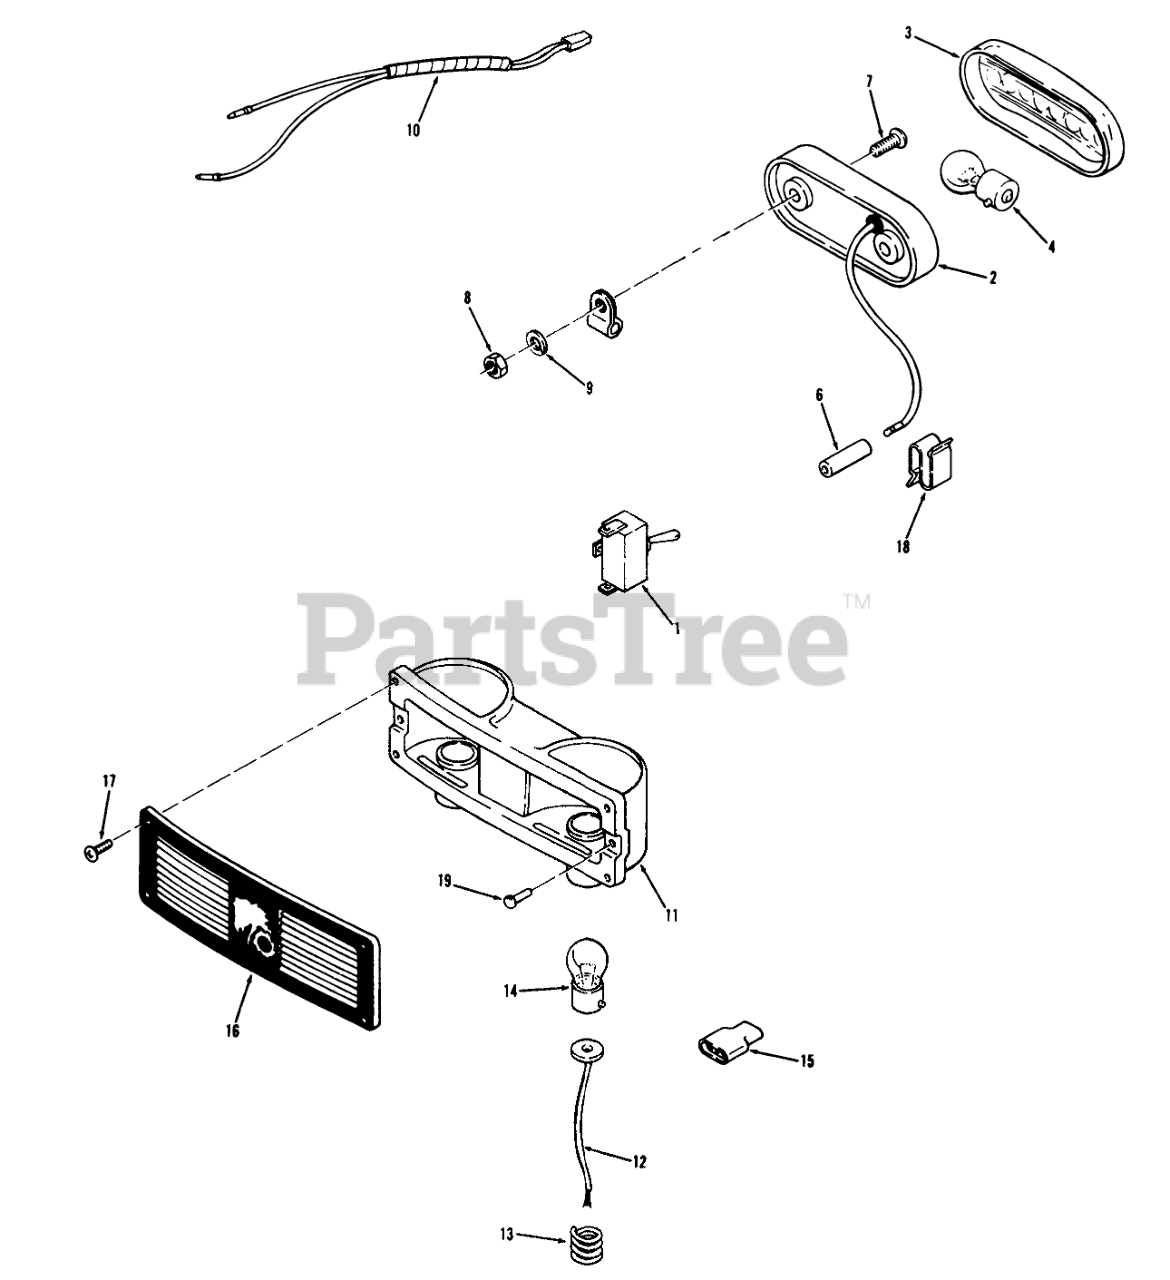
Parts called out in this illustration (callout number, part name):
1	SWITCH-LIGHTS
2	Base-Taillight
3	Lens-Taillight
4	Bulb
6	CONNECTOR 2 WIRE
7	Screw
8	Nut
9	Lockwasher
10	Wire Harness-Lights
11	ASSY REFLECTOR HOUSI
12	WIRE ASSY
13	SPRING
14	BULB
15	CONNECTOR 3 WIRE
16	Lens
17	Pan HD Swage
18	SPEED CLIP
19	Pop Rivet
